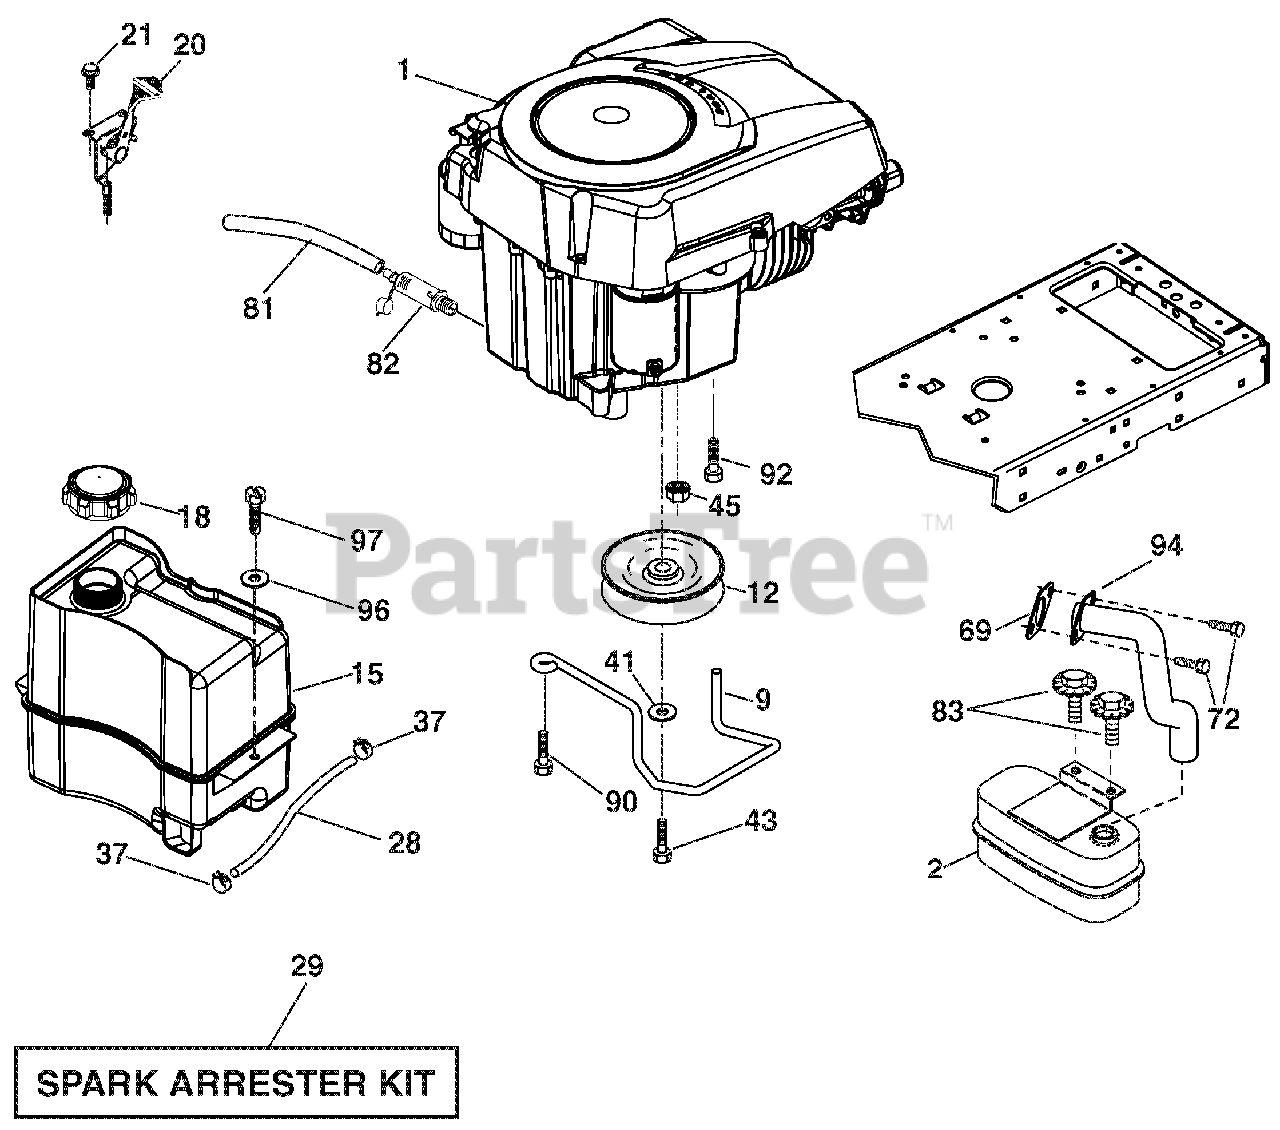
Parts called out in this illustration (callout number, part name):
2	MUFFLER.SINGLE.CYL.KOHL.COURAG
9	KEEPER.BELT.ENGINE.3.25"NSTL
12	PULLEY.ENGINE
15	TANK.FUEL.FRT.N/CAP.1.5GAL.DAP
18	CAP ASM.FUEL.TOP.125/2.5.LTTEX
20	CONTROL.TH/CK.COBRA.BS.EEC.428
28	LINE.FUEL.22"FRONT.EMIS.CA.LP
29	KIT.SPARK ARRESTOR(392390 B&S)
37	CLAMP.HOSE.BLK.
41	WASHER.LOCK.HVY HLCL.SPR.7/16
43	BOLT.HEX.7/16-20X4XGR5-1.5THR.
45	Nut, Keps Hex 1/4-20 unc
69	GASKET.KOHLER.SV.I.
72	SCREW.SOCKET HD.5/16-18 X .75
81	TUBE.DRAIN.OIL.EASY
82	PLUG.DRAIN.OIL.EASY
83	BOLT.5/16-18UNCX3/4 W/SEMS.BLK
90	SCREW.3/8-16X1.SMGML.TAP/R.BLK
92	SCREW.3/8-16 X 1.SMGML.TAP/R
94	TUBE.EXHAUST.KOHL.COURAGE
96	WASHER.9/32 X 7/8 X 16GA.
97	SCREW.HEXWSH.THDROL.1/4-20X3/4
